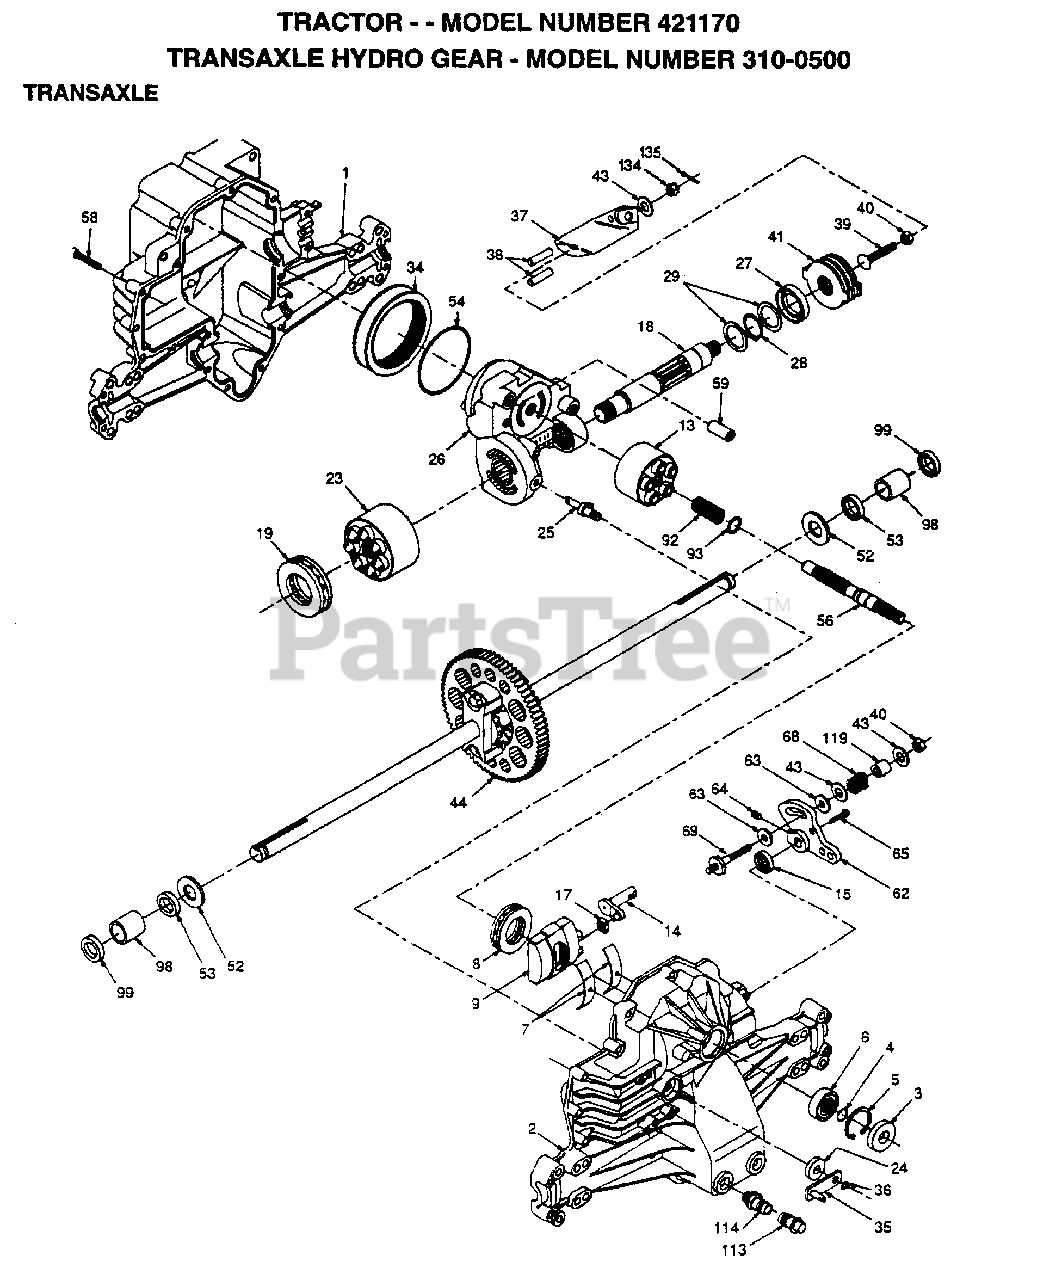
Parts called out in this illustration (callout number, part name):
1	HOUSING.L.44863RM
2	HOUSING.UPR.70122
3	SEAL.9008000-0128
4	RING.RET.2003016.
5	RING.RET.2003052.
6	BEARING.(50552)42X68X16
7	CRADLE- 2003023.
8	BEARING.2003044.
9	SWASHPLT.2003087.
13	BLOCK.CLYN.70079.
14	ARM.TRUN.2003005.
15	SEAL.9008000-0126
17	GUIDE.2000015.
18	SHAFT.HYD.2003557
19	BEARING.THS.50019
23	BLOCK.CYLIN.70082
24	SEAL.LIP.45074
25	ACTUATOR.2003555
26	KIT.CENTER.70133
27	SEAL.LIP.45075
28	RING RETAIN 50007
29	WASHER.44872
34	ELEMENT.OIL.44964
35	ARM.BYPASS.50270
36	RING.RETAIN.44870
37	ARM.ACTUAT.23710
38	PIN.ACTUAT.44891
40	NUT.LOCK.HX.50108
41	KIT.BRAKE.70135
43	WASHER HYD 44130
44	DIFFERNTIAL.70126
52	WASHER.HYD.44875
53	SEAL.HYDRO.45076
54	O RING.HYD.45077
56	SHAFT.INPUT.50005
58	BOLT.1/4-20.44876
59	PIN.HYDRO.50002
62	ARM.CONTROL.50254
63	PUCK.DAMPER.50281
64	SCREW.SET.50018.
65	BOLT #8-32 X .875
68	SPRING.HYD.50277
69	STUD.5/16-24.DANA
92	SPRING.2003014.
93	WASHER.2003017
98	BEARING.SLV.50137
99	SEAL.WIPER.50941
113	CAP.VENT.70109
114	O-RING.ASM.70110
119	SPACER.HYD.50278
134	NUT.CAS.HYD.44142
135	PIN.COT.HYD.44101
